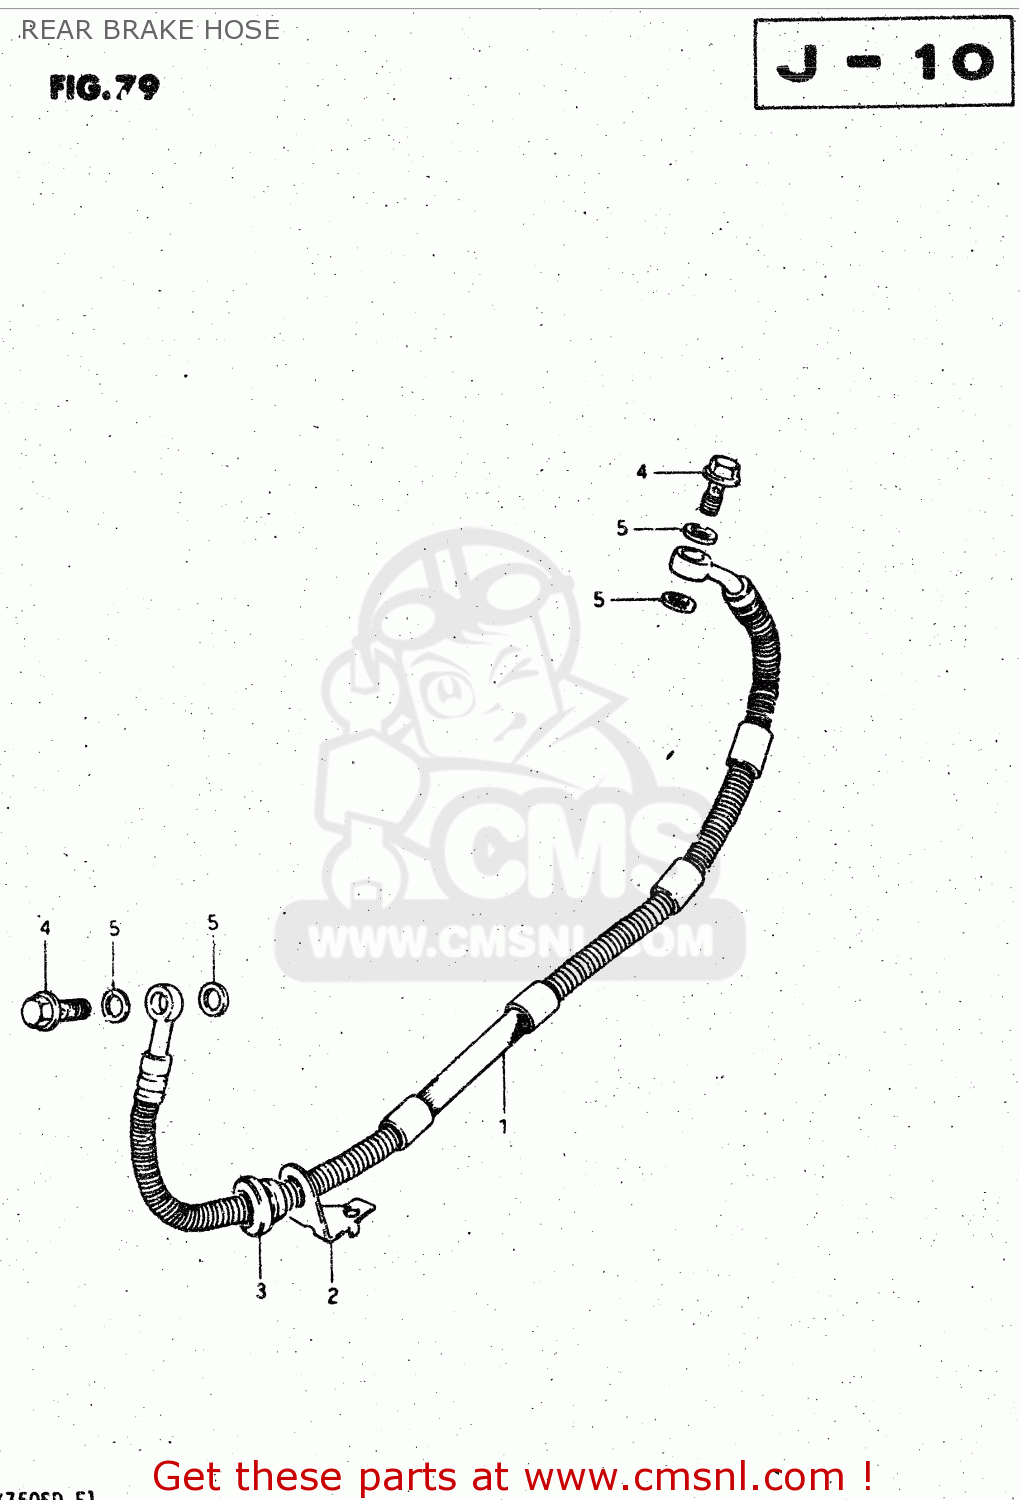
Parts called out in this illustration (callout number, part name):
1	HOSE,REAR BRAKE
2	GUIDE,BRAKE HOSE
3	GROMMET,BRAKE HOSE GUIDE
4	BOLT,UNION
5	WASHER
